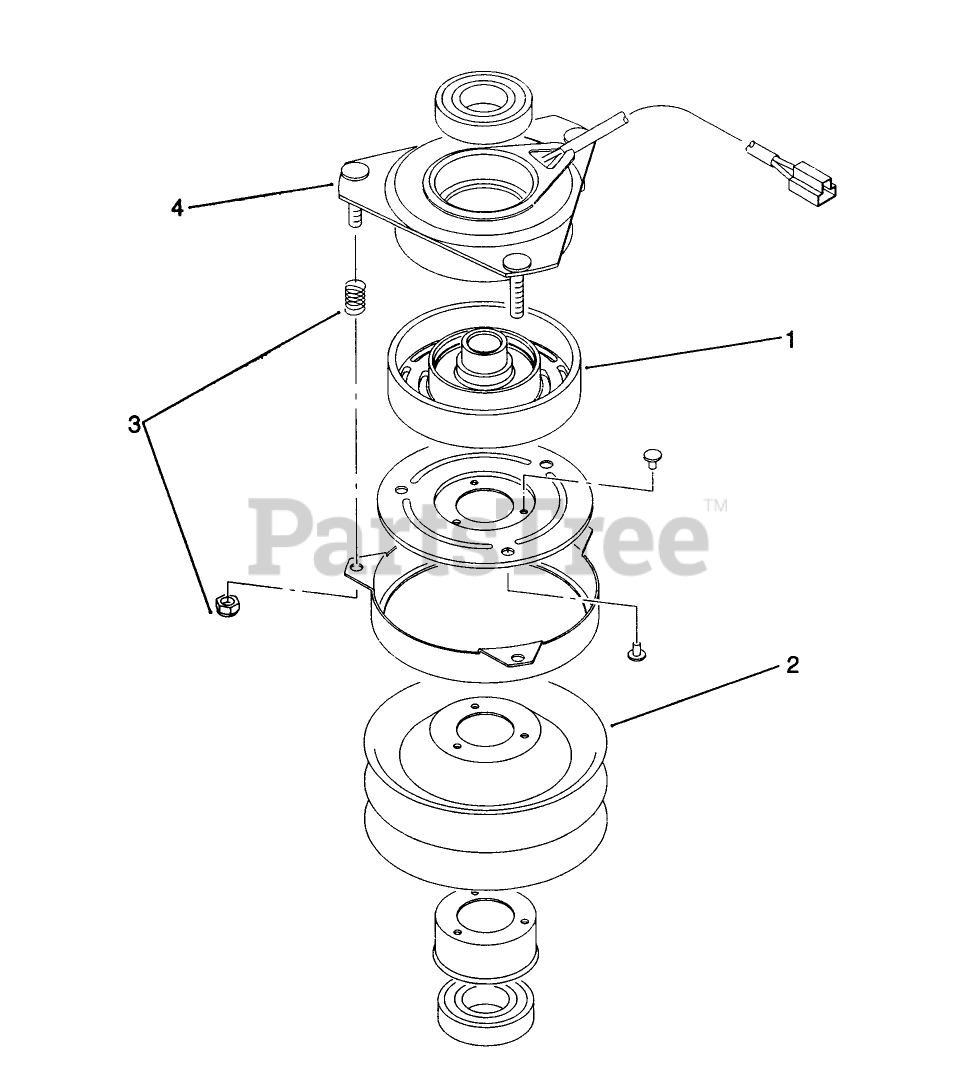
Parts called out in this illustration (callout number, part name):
1	Assembly-Rotor
2	Assembly-Armature
3	Accessories-Nuts Springs
4	Assembly-Field
